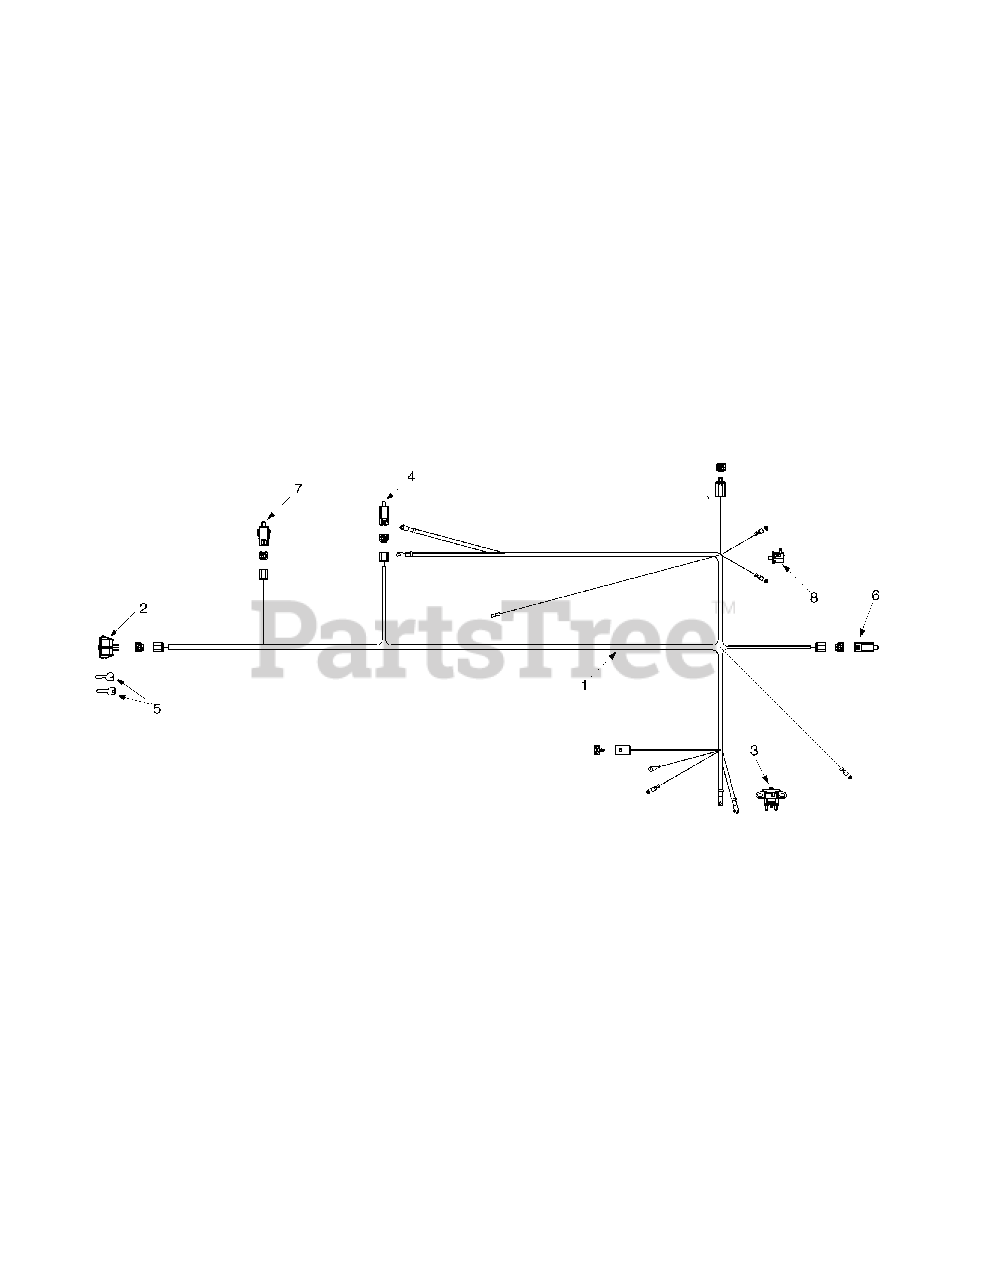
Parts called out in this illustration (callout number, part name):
1	Harness Assembly
2	Key Switch
3	Solenoid: 12 V. 100 amp.
4	Interlock Switch
6	Switch: Plgr N.C./N.C.
7	Switch: Plgr N.O./N.C.
8	Switch: Mt. Snap N.C.
